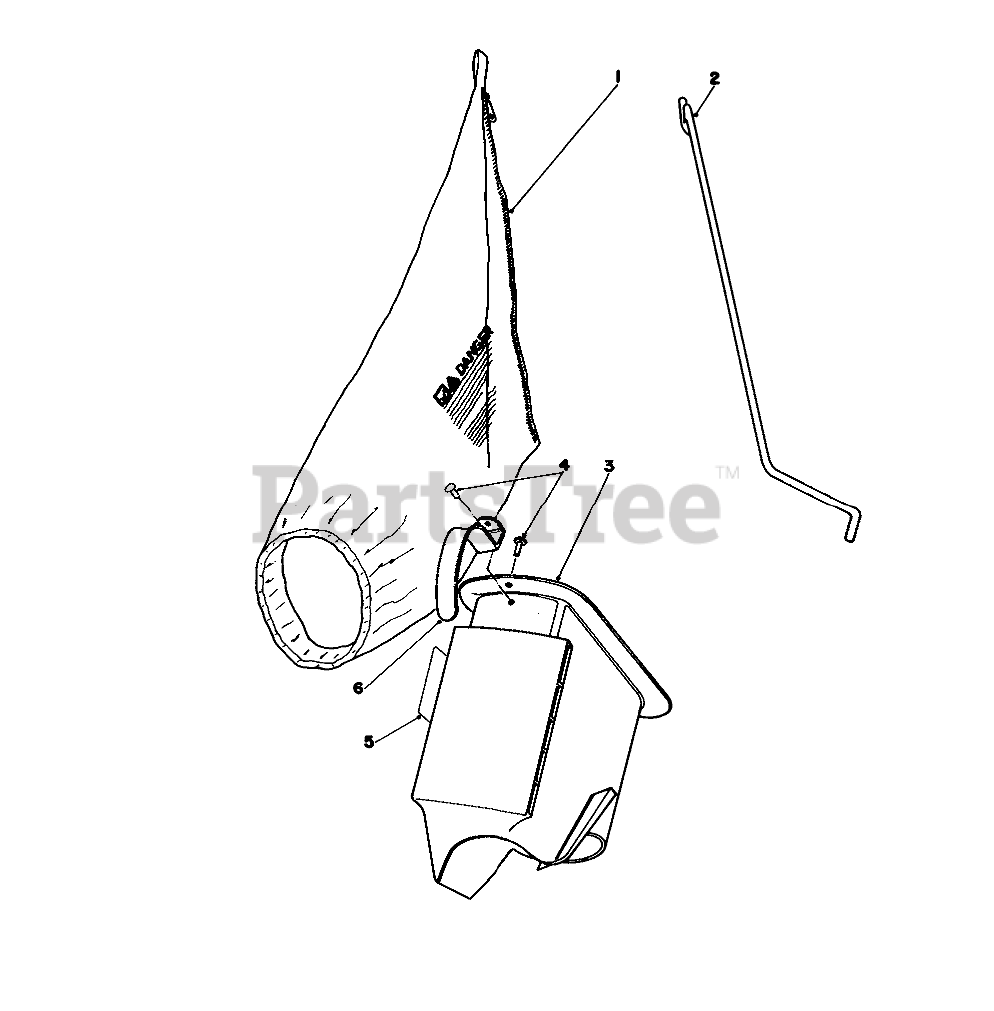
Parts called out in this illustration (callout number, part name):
1	BAG REPLACMNT44-0540
2	BAG ROD
3	Grass Chute (Incl. Ref. #4 & 6)
4	RIVET 3/16 X 7/16
5	BAG CHUTE DECAL
6	HANDLE-GRASS CHUTE
